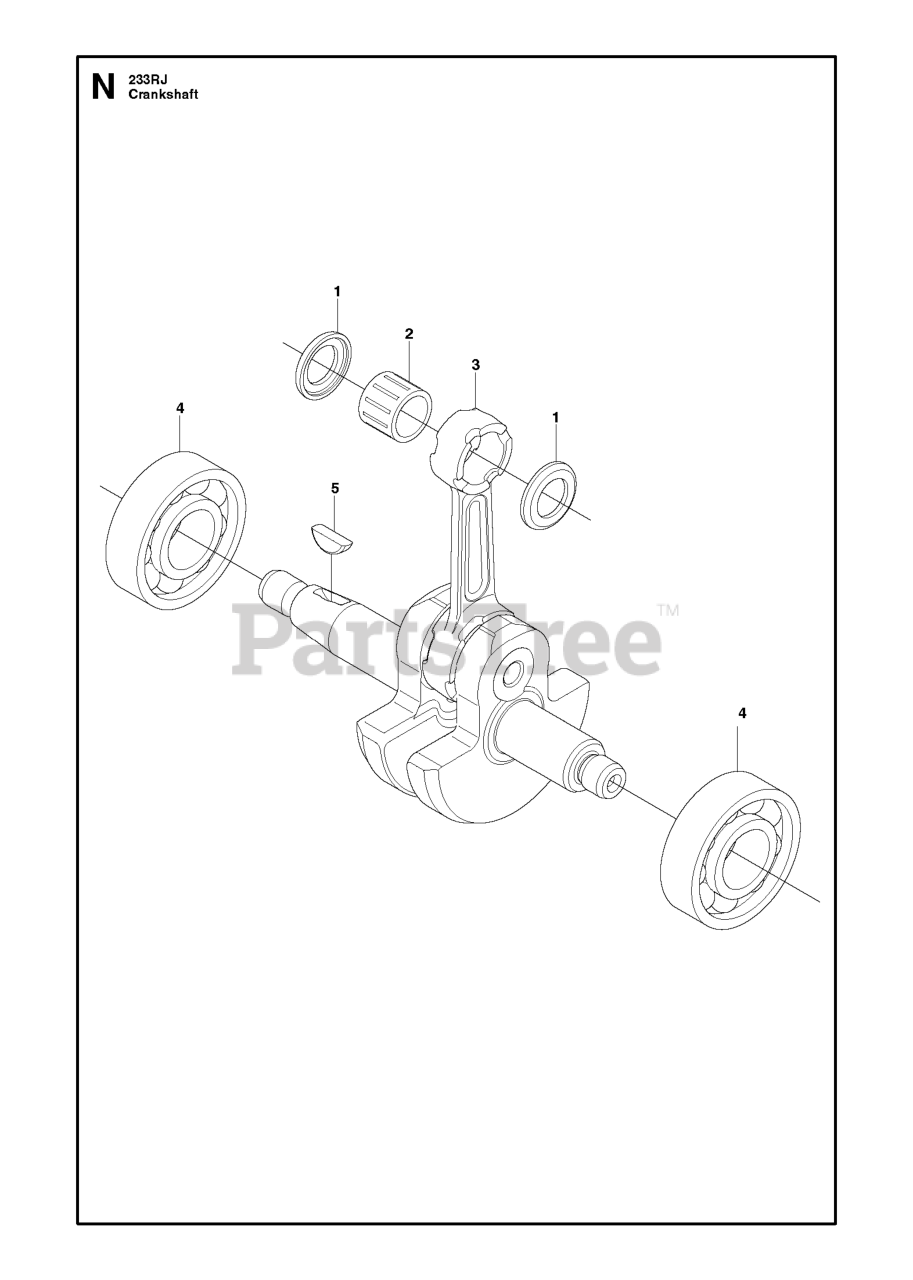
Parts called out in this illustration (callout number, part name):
1	WASHER
2	BEARING
3	CRANKSHAFT-C
4	BEARING
